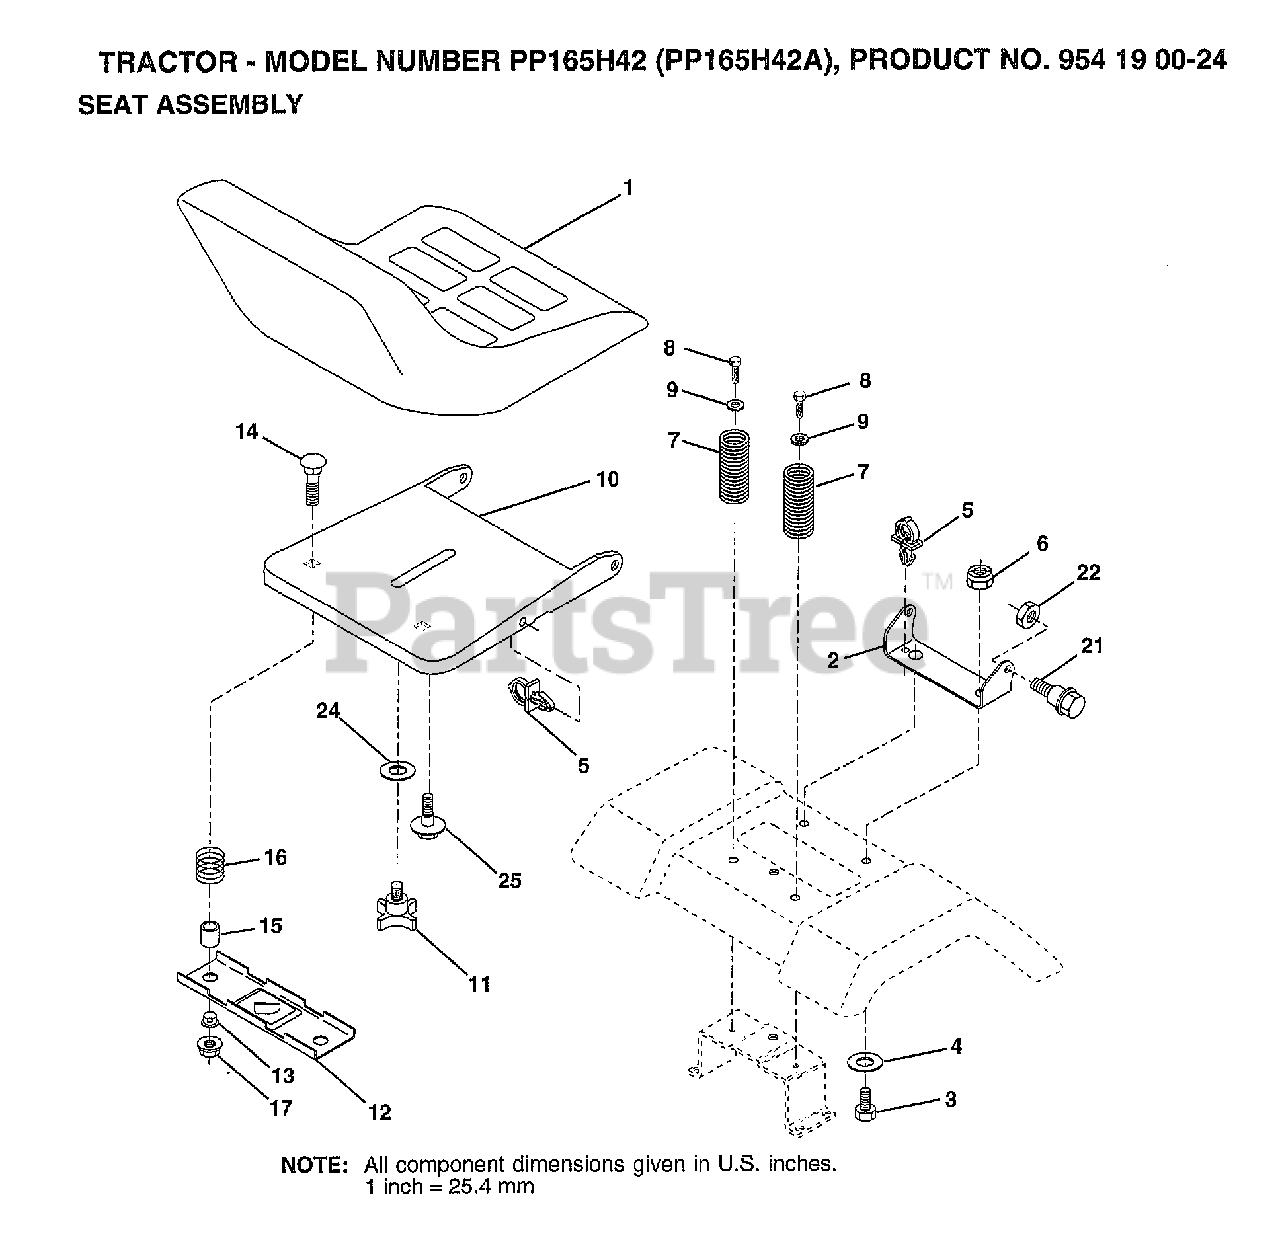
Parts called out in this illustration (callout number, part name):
1	SEAT.2400/1416.BK
2	BRACKET PVT SEAT
3	BOLT
4	WASHER PM
5	CLIP.PUSH-IN.HING
6	NUT
7	SPRING, COMPRESSION, SEAT
8	SCREW GTV
9	WASHER
10	PAN-SEAT
11	"KNOB 1/2"" YT"
12	BRKT SWITCH
13	BUSHING
14	BOLT-RD HD SQ NK
15	SPLIT SPACER
16	SPRING
18	CAP SPRING
21	"BOLT,SHOULDER"
22	NUT
24	WASHER
25	"BOLT,SHOULDER"
